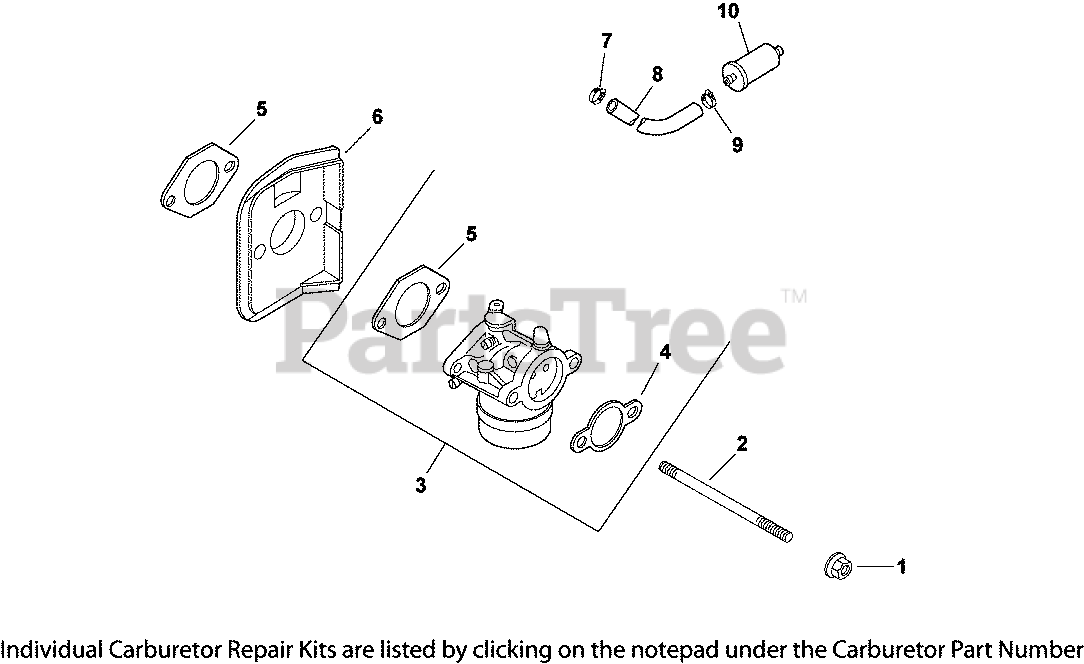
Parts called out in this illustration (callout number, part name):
1	NUT, FLG M6X1.0
2	STUD,M6X1.0X116
3	KIT, CARB W/GASKETS - USE 12 853 177-S
4	GASKET, AIR CLEANER BASE
5	GASKET, CARBURETOR
6	DEFLECTOR, HEAT
7	CLAMP, HOSE (KM)-USE 25 237 31-S
8	HOSE,LW PERM.FUEL 24.00"-USE 25 111 81-S
9	CLAMP, BAND SPRING HOSE-(#2523737S)
10	FILTR,FUEL 75 MICRON (GRAVTY FEED)
